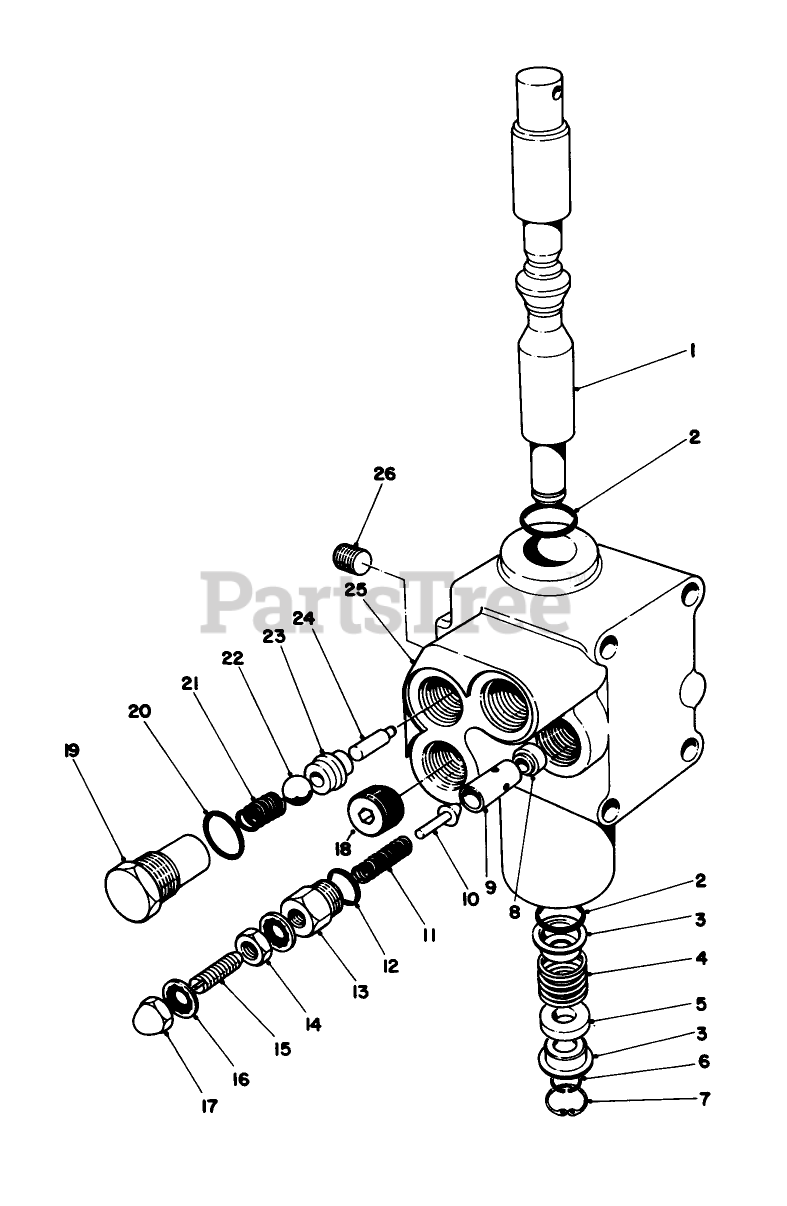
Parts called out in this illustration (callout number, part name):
1	SPOOL
2	O-RING
3	RETAINER
4	SPRING
5	FLOAT SPACER
6	RING-SNAP
7	RING-SNAP
8	SEAT-RELIEF
9	Guide
10	Plunger
12	"O" Ring
13	Cap-PV Adjustment
14	Jam Nut
15	Set Screw
16	Stat O-Seal
17	Nut-Acorn
20	O-RING
21	SPRING
23	SEAT-VALVE
